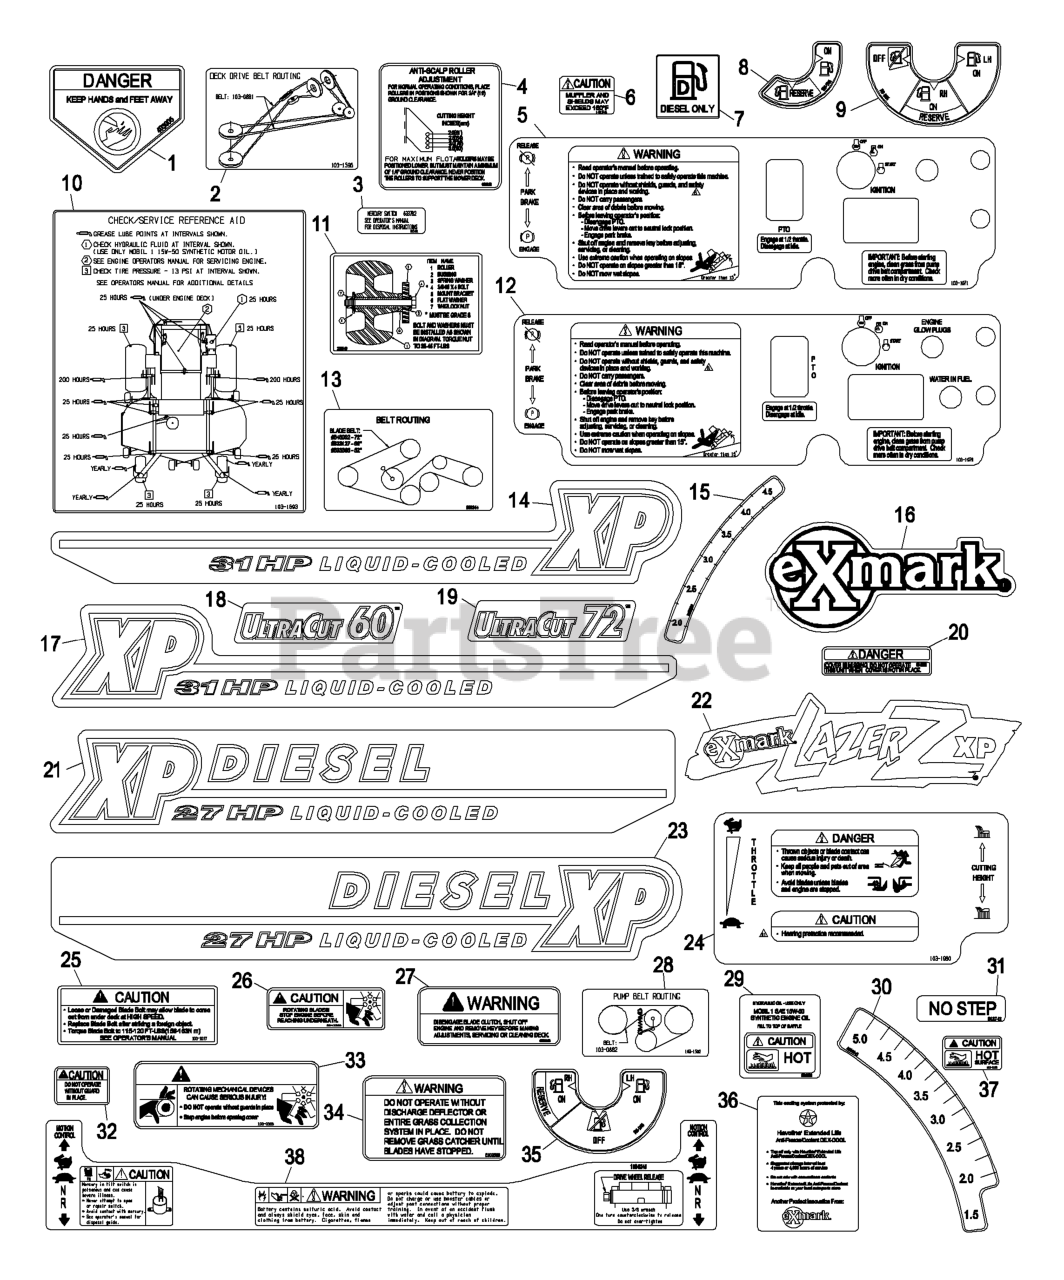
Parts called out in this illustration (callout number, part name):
1	DECAL-DANGER
2	DECAL,BELT ROUTING XP
3	DECAL-SWITCH, MERCURY
4	DECAL,ANTISCALP
7	DECAL-FUEL
10	DECAL,CHECK/SERVICE XP *
11	DECAL,ROLLER MOUNTING
13	DECAL,BELT ROUTING
15	DECAL-HEIGHT, DECK
18	DECAL,ULTRACUT 60
19	DECAL,ULTRACUT 72
20	DECAL-COVER, MISSING
25	DECAL,BOLT TORQUE
26	DECAL-FAN, RADIATOR
27	DECAL,WARNING
30	DECAL-HEIGHT, DECK
31	DECAL,NO STEP
32	DECAL-GUARD
34	DECAL-WARNING, DISCHARGE
35	DECAL, FUEL VALVE XPG
36	DECAL,SHELL COOLANT
37	DECAL-CAUTION
38	DECAL-CONSOLE, TOP
